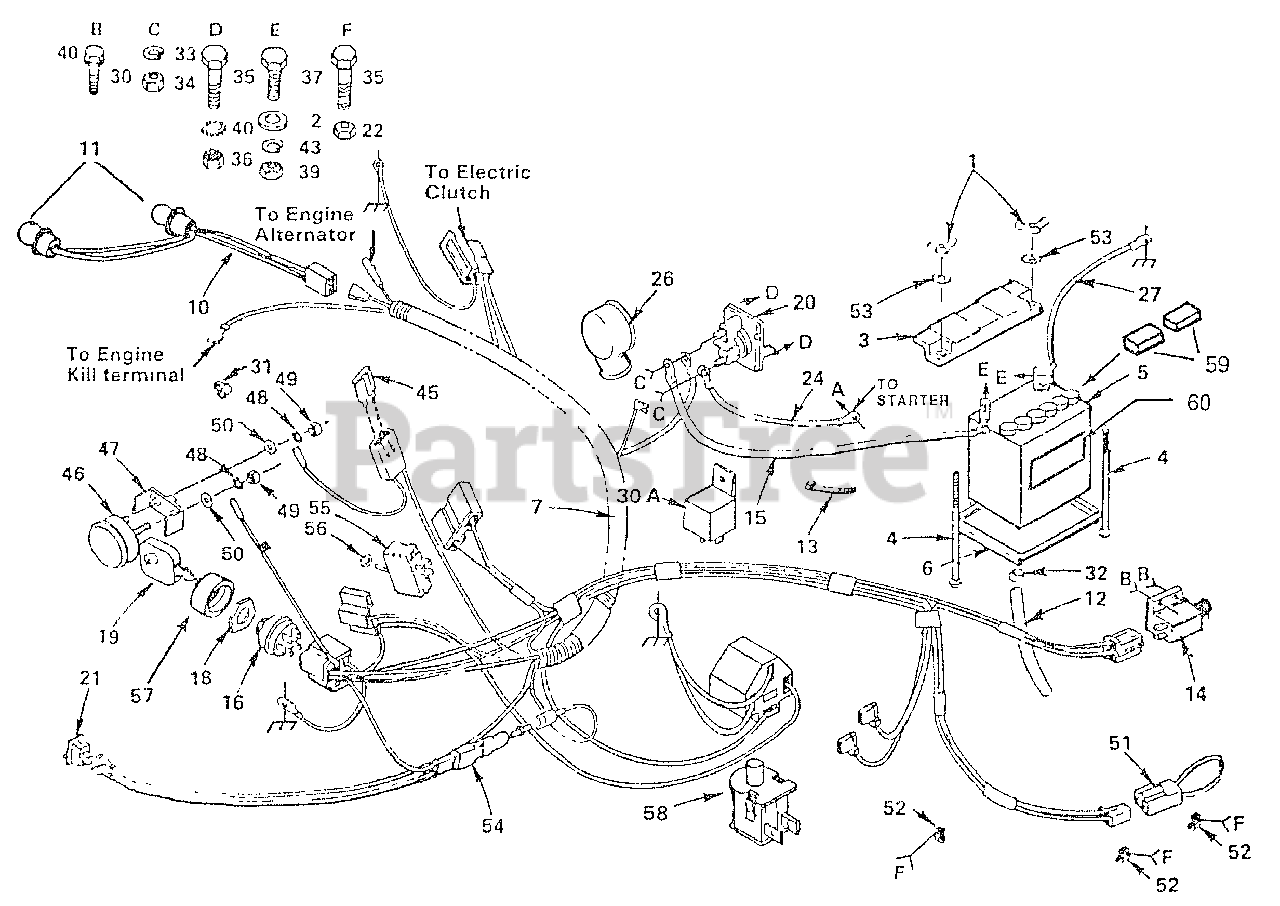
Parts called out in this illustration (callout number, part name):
1	Wing Nut 1/4-20
2	Washer 9/32 x 5/8 x 16 Ga
3	Guard-Terminal
4	Battery Bolt (Bolt-Carriage, Rd. Hd. Sq. Neck 1/4 20 x 7-1/21)
5	Battery
6	Battery Tray
7	Harness - Ignition
10	Harness-Light Socket
11	Bulb-Light
12	Tube-Battery Tray
13	Cable Tie
14	Switch - Interlock - Clutch
15	Cable-Battery (Battery to Solenoid)
16	Ignition Switch
18	Nut - Ignition
20	Solenoid
21	Switch-Light
22	Nut - Crownlock 1/4-20
24	Cable - Battery (Solenoid to Starter)
26	Terminal Cover (For Solenoid)
27	Cable-Battery (Battery to Ground)
30	Screw-Tap. Hex Hd. No. 10-24 ZINC
31	Clip-Fuel Line
32	Clamp-Hose
33	Lockwasher 1/4
34	Nut-Hex Jam 1/4-20
35	Bolt-Hex 1/4-20 x 1/2 Gr. 5
36	Nut- Keps, Hex 1/4-20
37	Bolt-Hex 1/4-20 x 3/4
39	Nut-Hex 1/4-20
40	Washer-Lock 1/4 Ext. Tooth
43	Lockwasher 1/4
45	Fuse-30 Amp.
47	Bracket-Ammeter
48	Lockwasher No. 10
50	Washer 7/32 x 1/2 x 18 Ga.
51	Loop-Wire Tiller Attachment
52	Clip -Insulated
53	Lockwasher - Int/Ext. Tooth, 1/4
54	Diode Assembly
55	Switch PTO
56	Nut-Hex
57	Bezel, Ignition
58	Switch, Plunger
59	Caps, Battery Set
60	Decal - Battery
